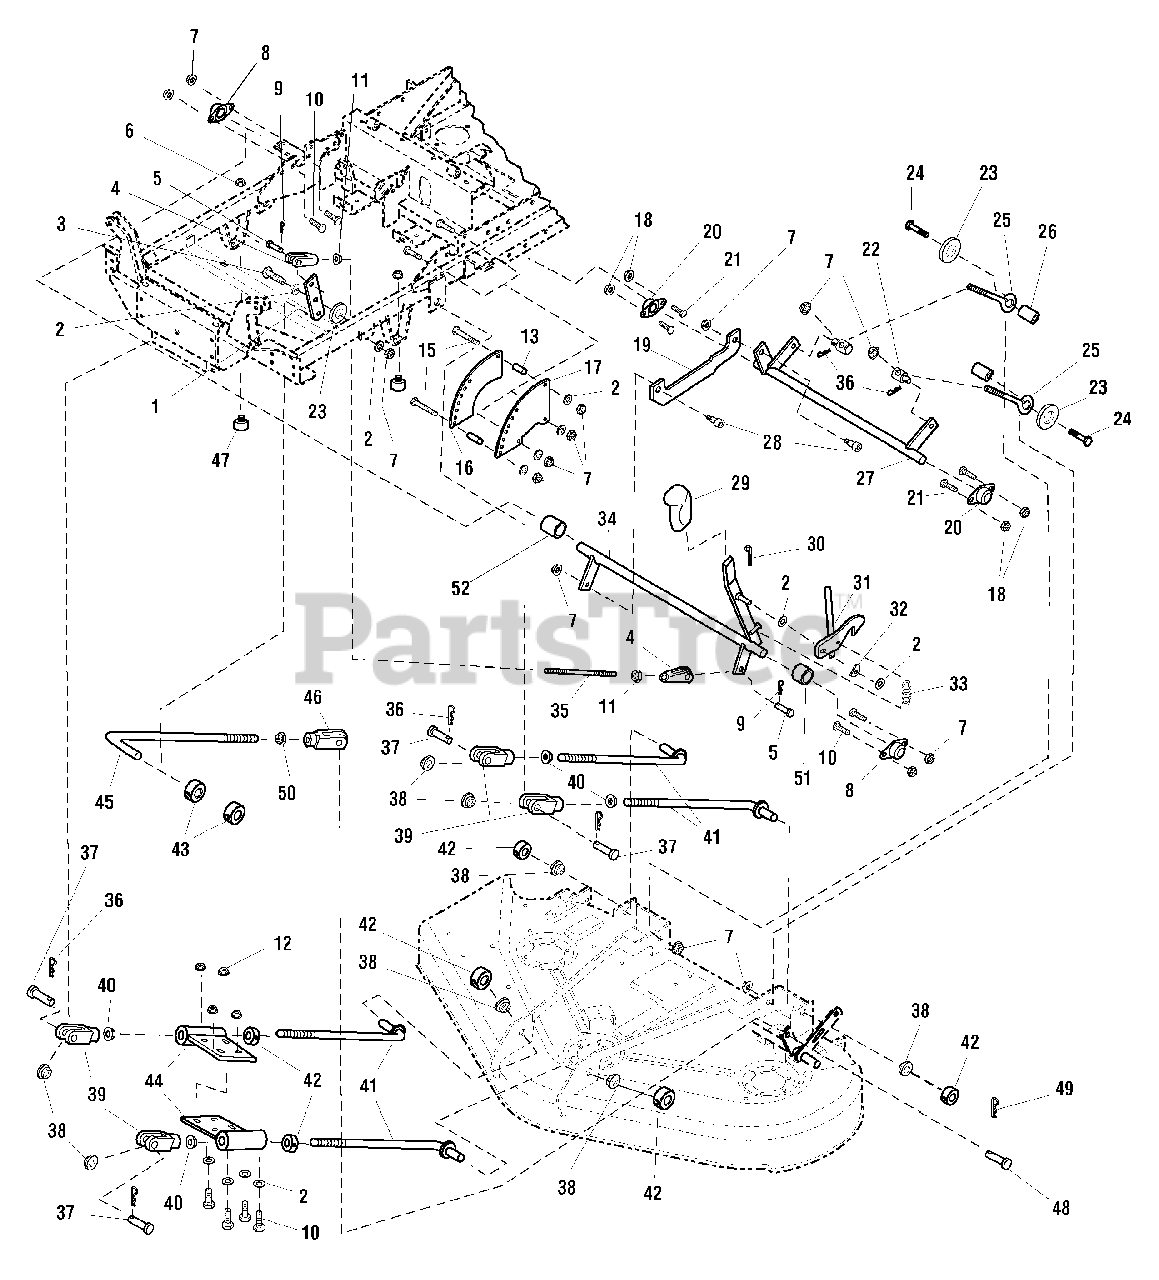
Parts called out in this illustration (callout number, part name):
1	REVERSING LINK
2	WASHER, 3/8, SAE
3	CAPSCREW, Hex Head, 3/8-16 X 1-1/2
4	PLASTIC CLEVIS, 3/8-24
5	PIN, 3/8 DIA X 1"
6	HEX NUT, Serrated Flange, 1/4-20
7	NUT, Hex Nylon Lock, 3/8-16
8	BEARING, Flange, Bronze, 3/4"
9	PIN, Cotter
10	CAPSCREW, Hex Head, 3/8-16 X 3/4
11	JAM NUT, Hex, 3/8-24
12	HEX NUT, Serrated Flange, 3/8-16
15	CAPSCREW, Hex Head, 3/8-16 X 2-1/2
16	DECK HEIGHT PLATE, Inner, Orange
16	DECK HEIGHT PLATE, Inner, Red
17	DECK HEIGHT PLATE, Outer, Orange
17	DECK HEIGHT PLATE, Outer, Red
18	HEX NUT, Nylon Lock, 5/16-18
19	LINK, Drift Lift, Orange
19	LINK, Drift Lift, Red
20	BUSHING, Bronze Flange
21	CAPSCREW, Hex Head, 5/16-18 X 3/4
22	ADJUSTER, Brake Linkage
23	WASHER, 1-3/4 OD X .390 ID
24	CAPSCREW, Hex Head, 3/8-16 X 1-3/4
25	EYE BOLT, 3/8-16 X 6, 3.0 THRD, 1 EYE
27	LIFT SHAFT, Rear Deck, Orange
27	LIFT SHAFT, Rear Deck, Red
28	BOLT, 1/2" X 3/8" Shoulder
29	HANDLE, Cover
30	PIN, Cotter, 3/16 X 1-1/2
31	LOCK, Deck, Orange
31	LOCK, Deck, Red
32	SPRING WASHER, 3/8
33	SPRING, Extension
34	SHAFT, Deck Height, Orange
34	SHAFT, Deck Height, Red
36	HAIRPIN
37	PIN, Clevis, 1/2 X 1-1/2
38	BUSHING, Support
39	CLEVIS, 1/2-20
40	NUT, Hex Jam, 1/2-20
41	ROD, Deck Hanger
42	SPLIT COLLAR, 1/2"
43	SPLIT COLLAR, 1/2"
44	DECK STABILIZER, Orange
44	DECK STABILIZER, Red
45	CONNECTING ROD, Roller (44" DECK)
45	CONNECTING ROD, Roller (50" DECK)
46	CLEVIS, 1/2-20
47	BUMPER, Rubber, 1/4-20
48	PIN, Clevis, 1/2 X 1-1/2
49	HAIRPIN
50	NUT, Hex Jam, 1/2-20
51	SPACER, .76 X 1.00 X .50
52	SPACER, .76 X 1.00 X 1.00
